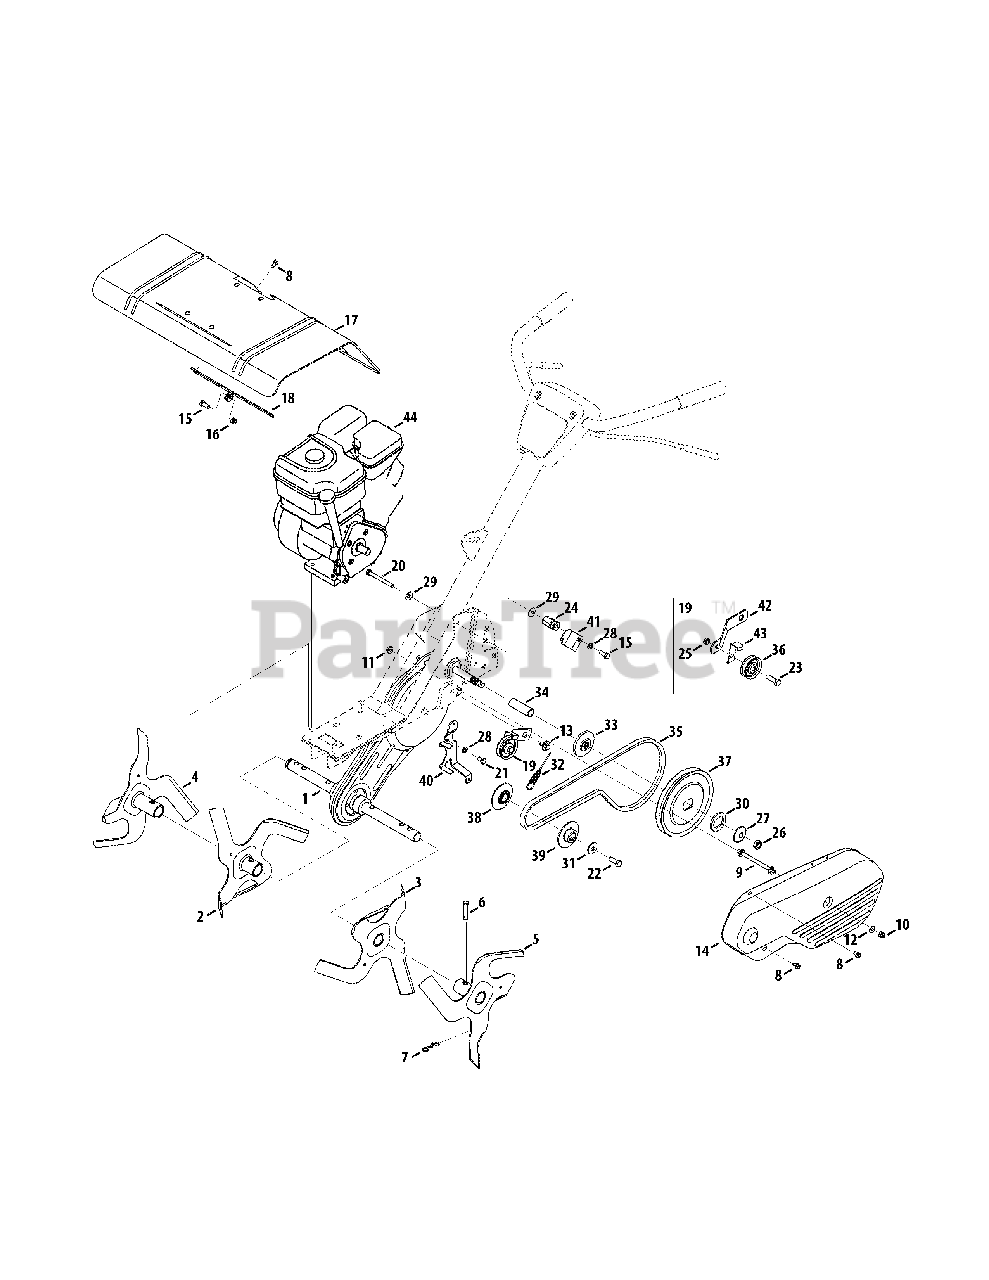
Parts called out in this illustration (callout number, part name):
1	Chain Case Assembly
2	Inner Tine Assembly, RH
3	Inner Tine Assembly, LH
4	Outer Tine Assembly, RH
5	Outer Tine Assembly, LH
6	Clevis Pin, .375 x 1.75
7	Bow Tie Cotter Pin
8	Screw, 1/4-20 x 0.500
9	Bolt, Belt Cover
10	Nut, 1/4-28, Lock
11	Nut, 5/16-18, Flange Lock
12	Flat Washer, .271 x .630 x .065
13	Shoulder Screw, .560 x .165 5/16-18
14	Belt Cover
15	Hex Head Screw, 5/16-18 x .75
16	Nut, 5/16-18, Flange Lock
17	Tine Shield
18	Bracket, Tine Shield
19	Idler Bracket Assembly
20	Hex Head Screw, 5/16-18 x 3.00
21	Hex Head Screw, 5/16-24 x .625
22	Hex Head Screw, 3/8-24 x 1.00
23	Hex Head Screw, 3/8-16 x 1.25
24	Hex Nut, 5/16-18
25	Jamlock Nut, 3/8-16
26	Nut, 1/2-20, Jam
27	Washer, .531 x 1.62 x .045
28	Lock Washer, 5/16
29	Bell Washer, .340 x .872 x .060
30	Flat Washer, 1.26 x 1.87 x .150
31	Bell Washer, .396 x 1.140 x .095
32	Forward Clutch Cable
33	Pulley Adaptor
34	Spacer, .64 ID x 2.4
35	Belt, 4L x 41.9 LG
36	Pulley 1.88 OD
37	Pulley 6.00 OD
38	Inner Engine Pulley
39	Outer Engine Pulley
40	Belt Keeper Bracket
41	Cable Guide Bracket
42	Idler Bracket
43	Belt Keeper
44	Replacement Engine 12T102-0751-F8
